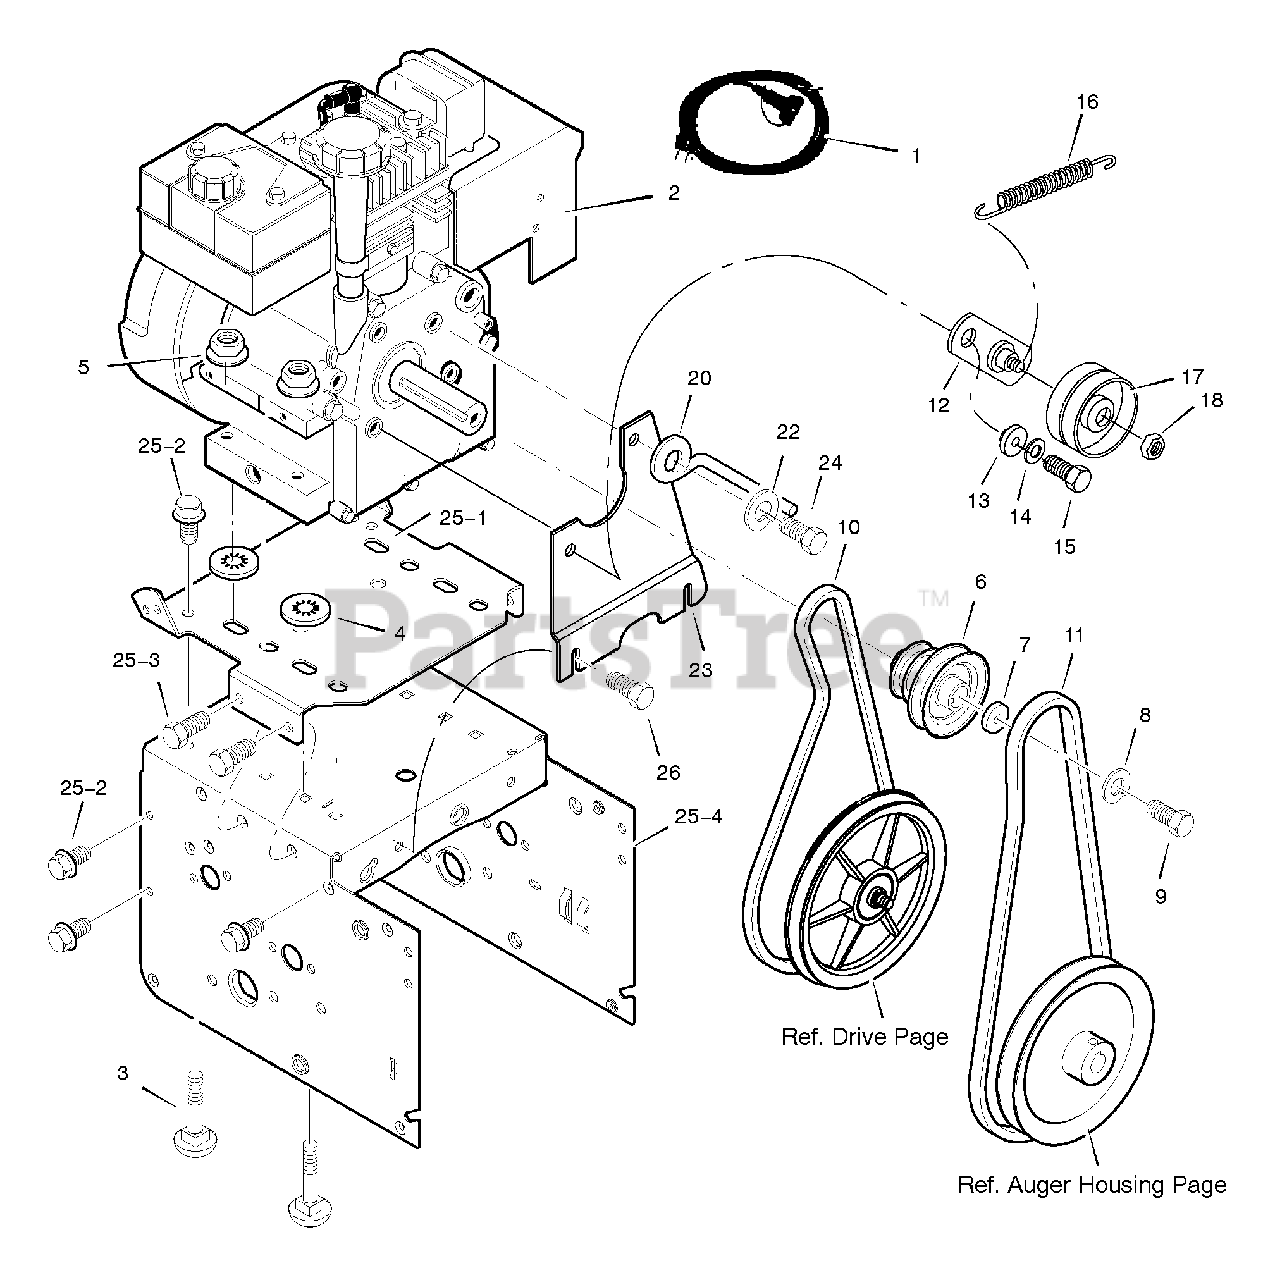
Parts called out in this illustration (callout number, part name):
1	CORD, Electric, 10FT. 110V
2	ENGINE *
3	BOLT, CARRIAGE 5/16-18
4	RETAINER, PUSH
5	NUT, HEX 5/16-18
6	PULLEY, ENGINE
7	WASHER
8	WASHER .38ID
9	SCREW, 3/8-24 x 1.00
10	BELT, DRIVE V 3L
11	BELT, AUGER V 4L
12	BRACKET ASSEMBLY, IDLER
13	BUSHING, IDLER BRACKET
14	WASHER, SPLIT
15	SCREW 5/16-24 X 1.00
16	SPRING, IDLER TRACTION DRIVE
17	PULLEY, IDLER
18	NUT, JAM 3/8-16
20	GUIDE, BELT
22	WASHER, SPTLK .31X.58X.08
23	PLATE, ANTI VIBRATION
24	SCREW, 5/16-24 x 1.00
25	FRAME ASSEMBLY
25-1	PLATE, ENGINE MOUNT
25-2	SCREW, TAP 1/4-20 X .63
25-3	SCREW, TAP 5/16-18 X .50
25-4	FRAME, MOTOR BOX
